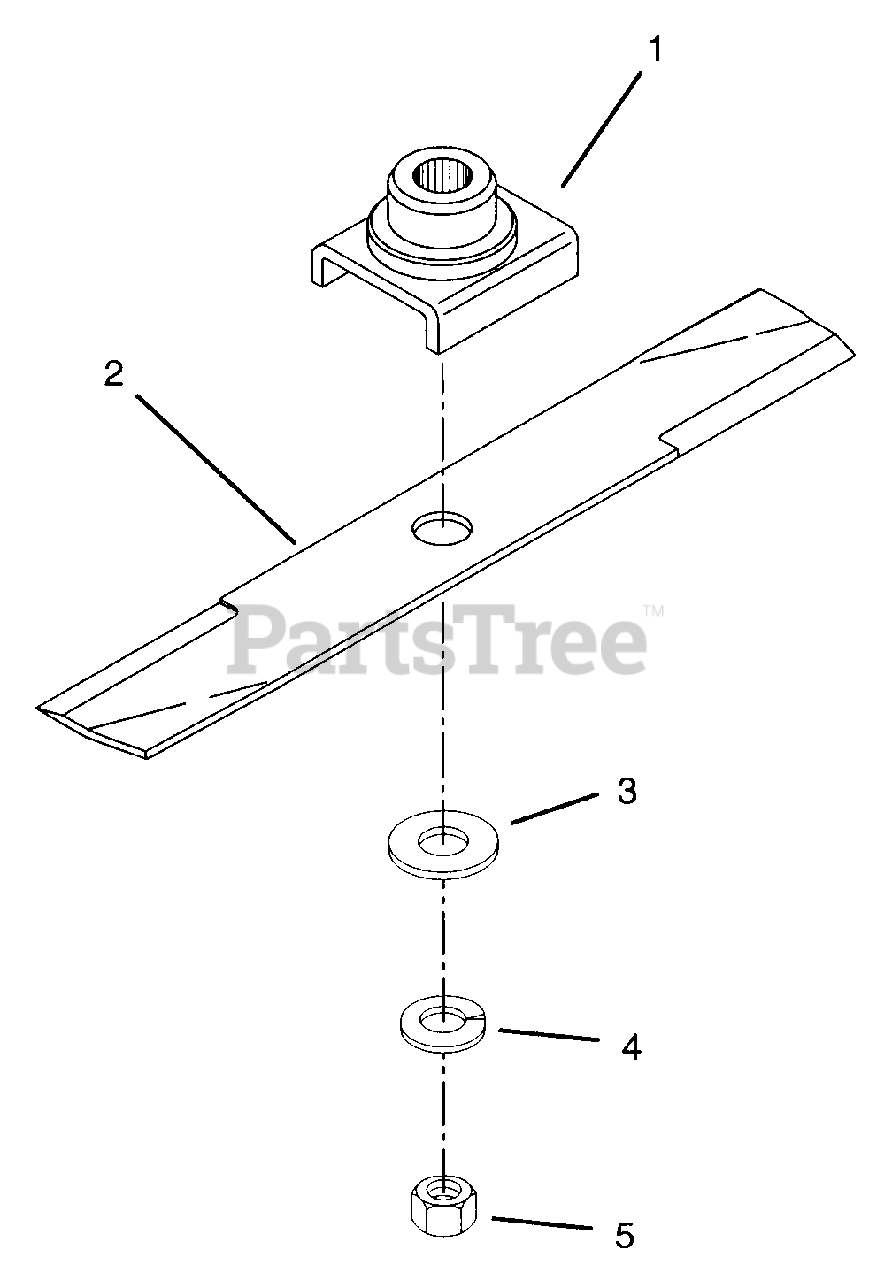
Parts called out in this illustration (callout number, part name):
1	Weldment, Blade Cradle
2	Blade, 60" Sand
3	Washer-Flat-Steel .656 x 1.312 x .095
4	Washer-Lock .625 x .156
5	Nut-Hex .625-11 Grade 2
